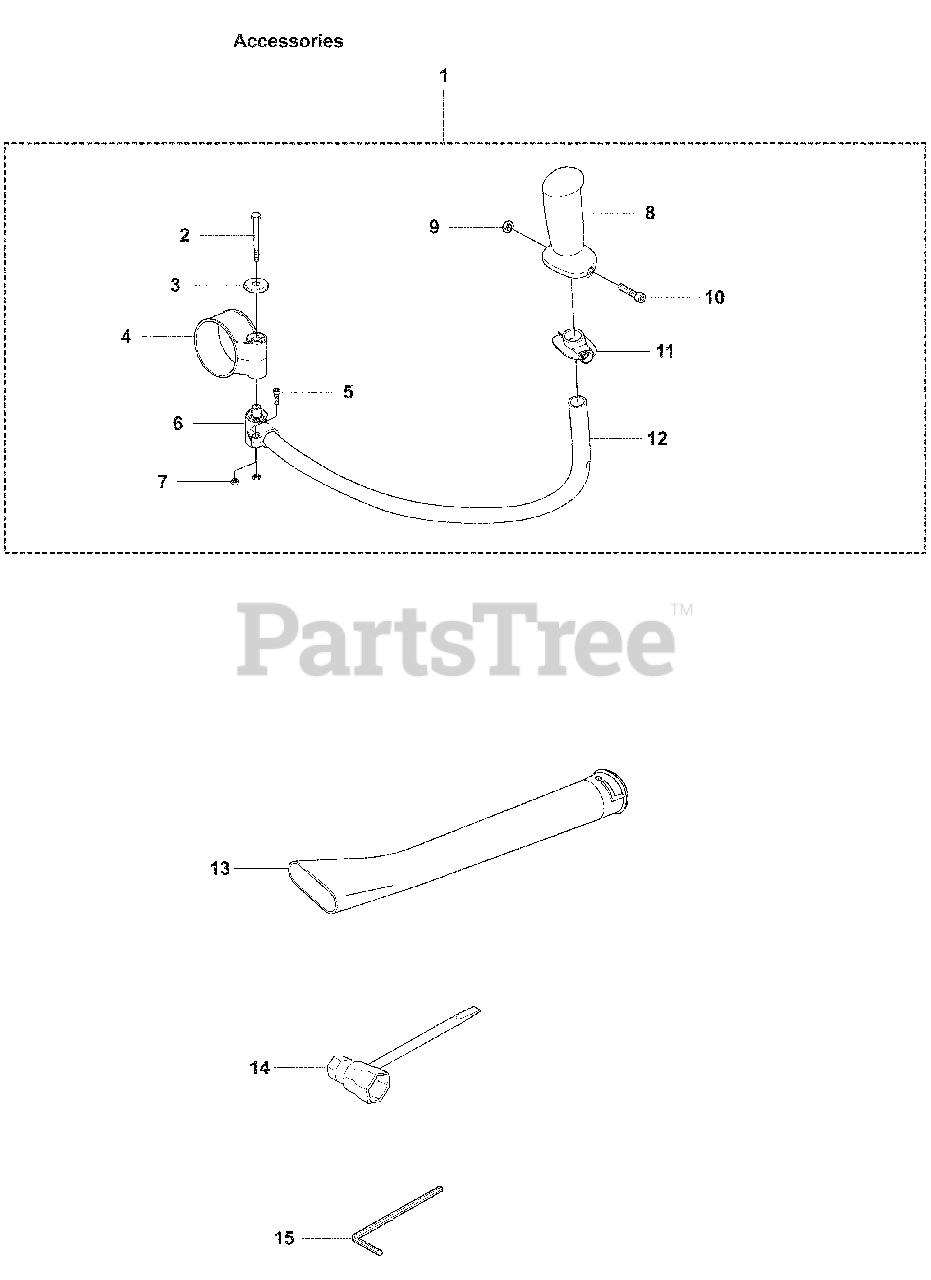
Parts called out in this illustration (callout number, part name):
3	Air Filter Cover Knob
5	Screw, MC6S 5 X 10
7	Hex Nut, M5 X .80 DIN
9	Hex Nut, M5 X .80 DIN
14	Combi Tool
